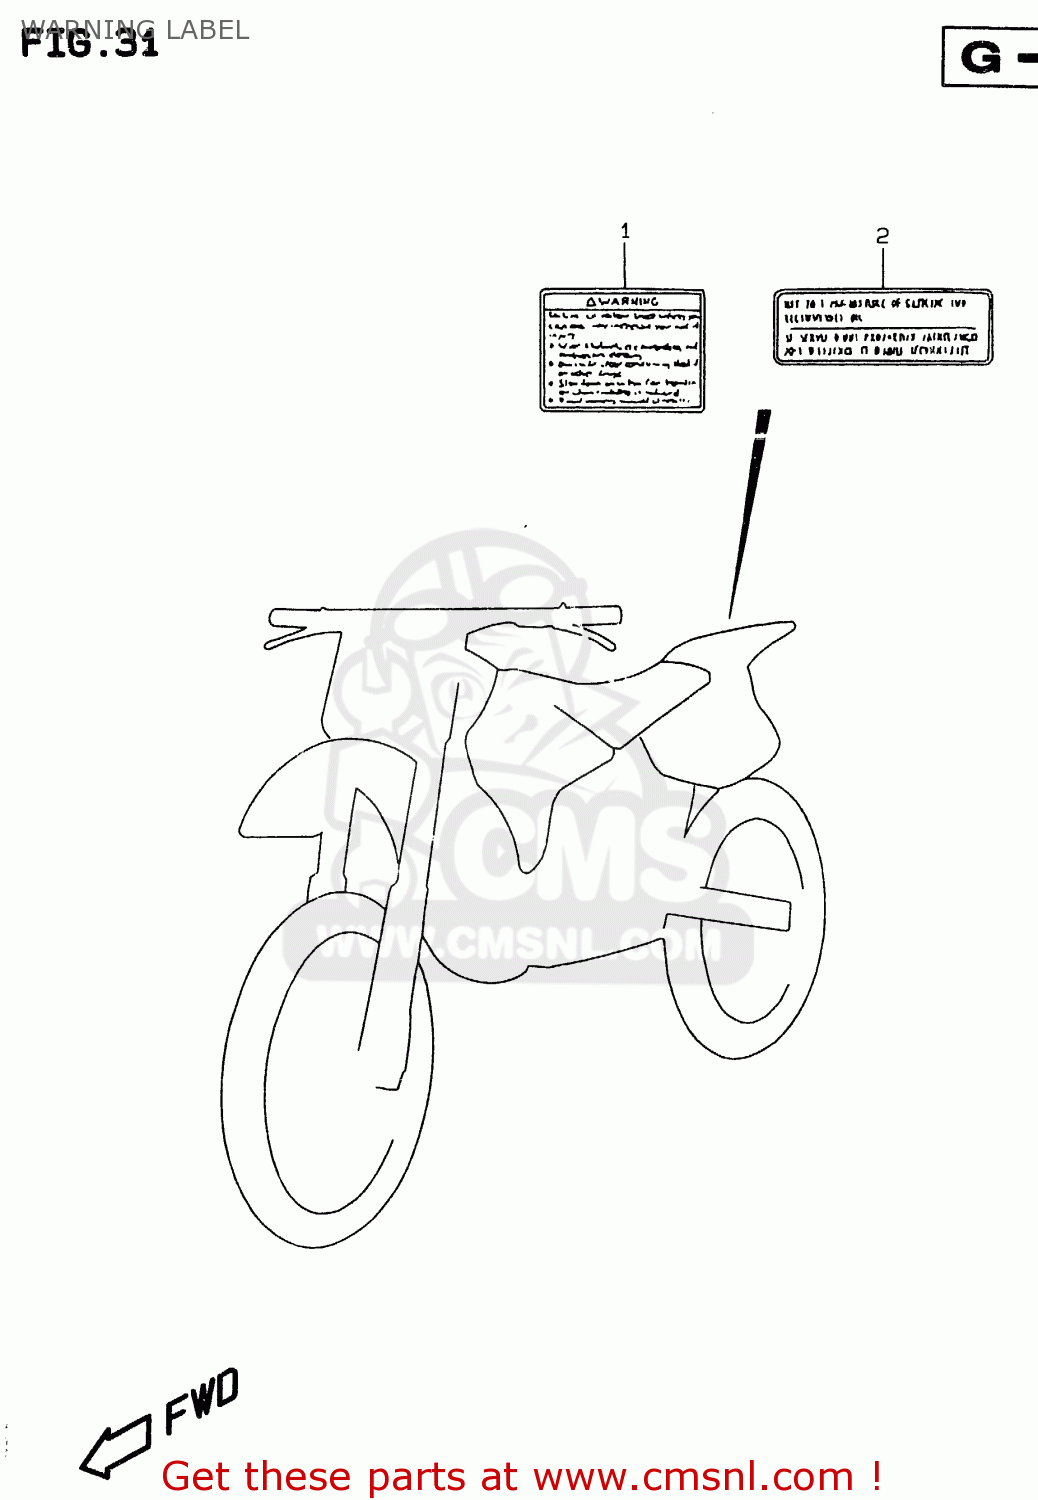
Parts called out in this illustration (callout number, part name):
1	LABEL (WARNING SAFETY),E
2	LABEL,WARNING NO.2
3	MANUAL, OWNER'S
